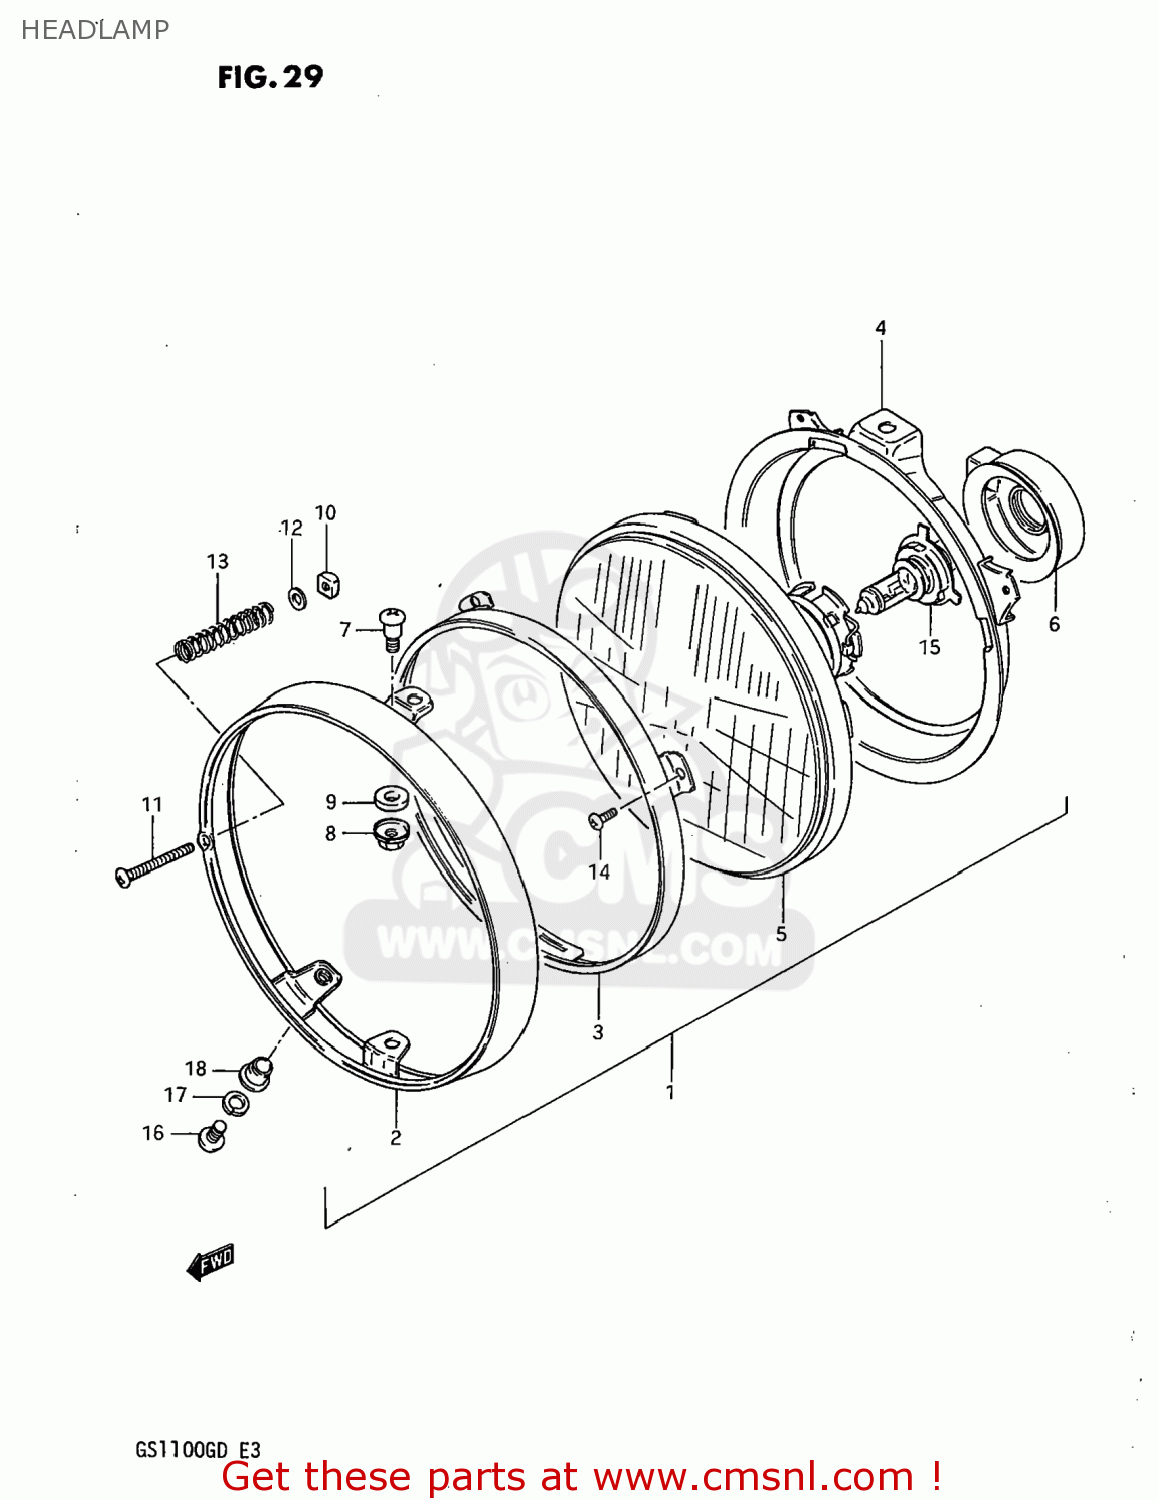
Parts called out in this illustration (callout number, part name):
1	HEADLAMP ASSEMBLY
2	RIM
3	RETAINER
4	RING,HEADLAMP UNIT
5	LAMP UNIT
6	COVER,HEADLAMP SOCKET
7	SCREW
8	NUT,ADJUSTING
9	SPACER
10	NUT
11	SCREW
12	WASHER
13	SPRING,HEADLAMP ADJUST
14	SCREW
15	BULB(12V60/55W,H4)
16	SCREW
17	WASHER,LOCK
18	WASHER
